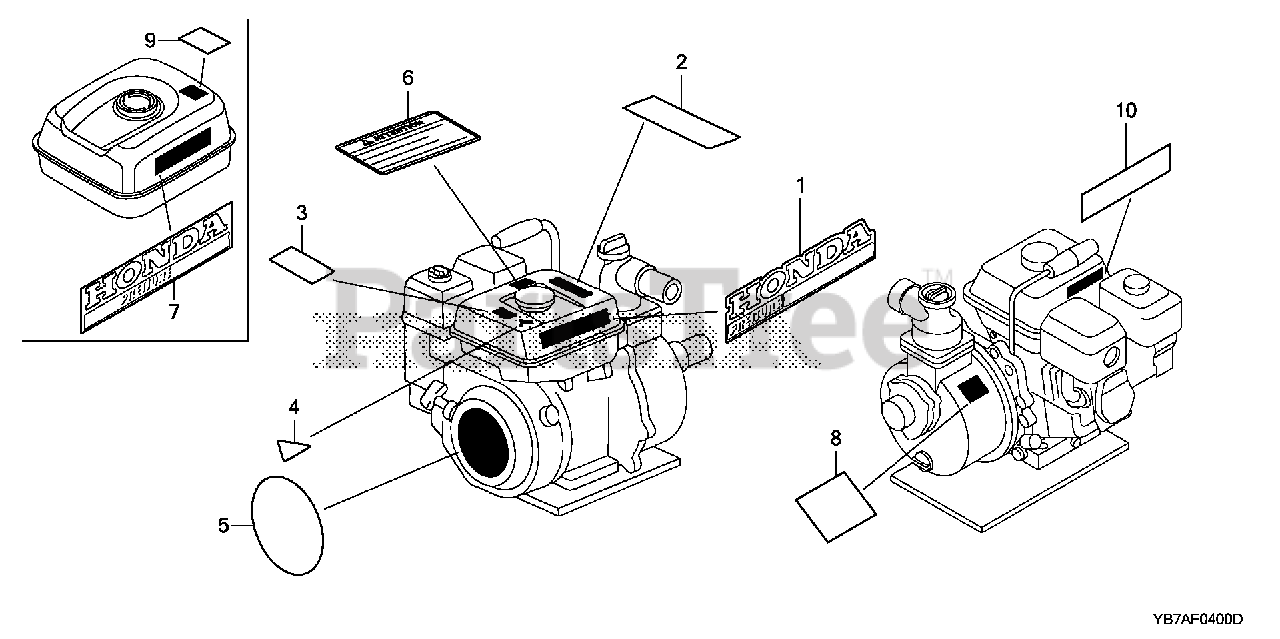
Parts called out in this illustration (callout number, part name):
1	MARK (WH20X)
2	MARK, CAUTION (PUMP)
3	LABEL, PUMP WARNING (ENGINE NO.)
4	LABEL, RENTAL USE
